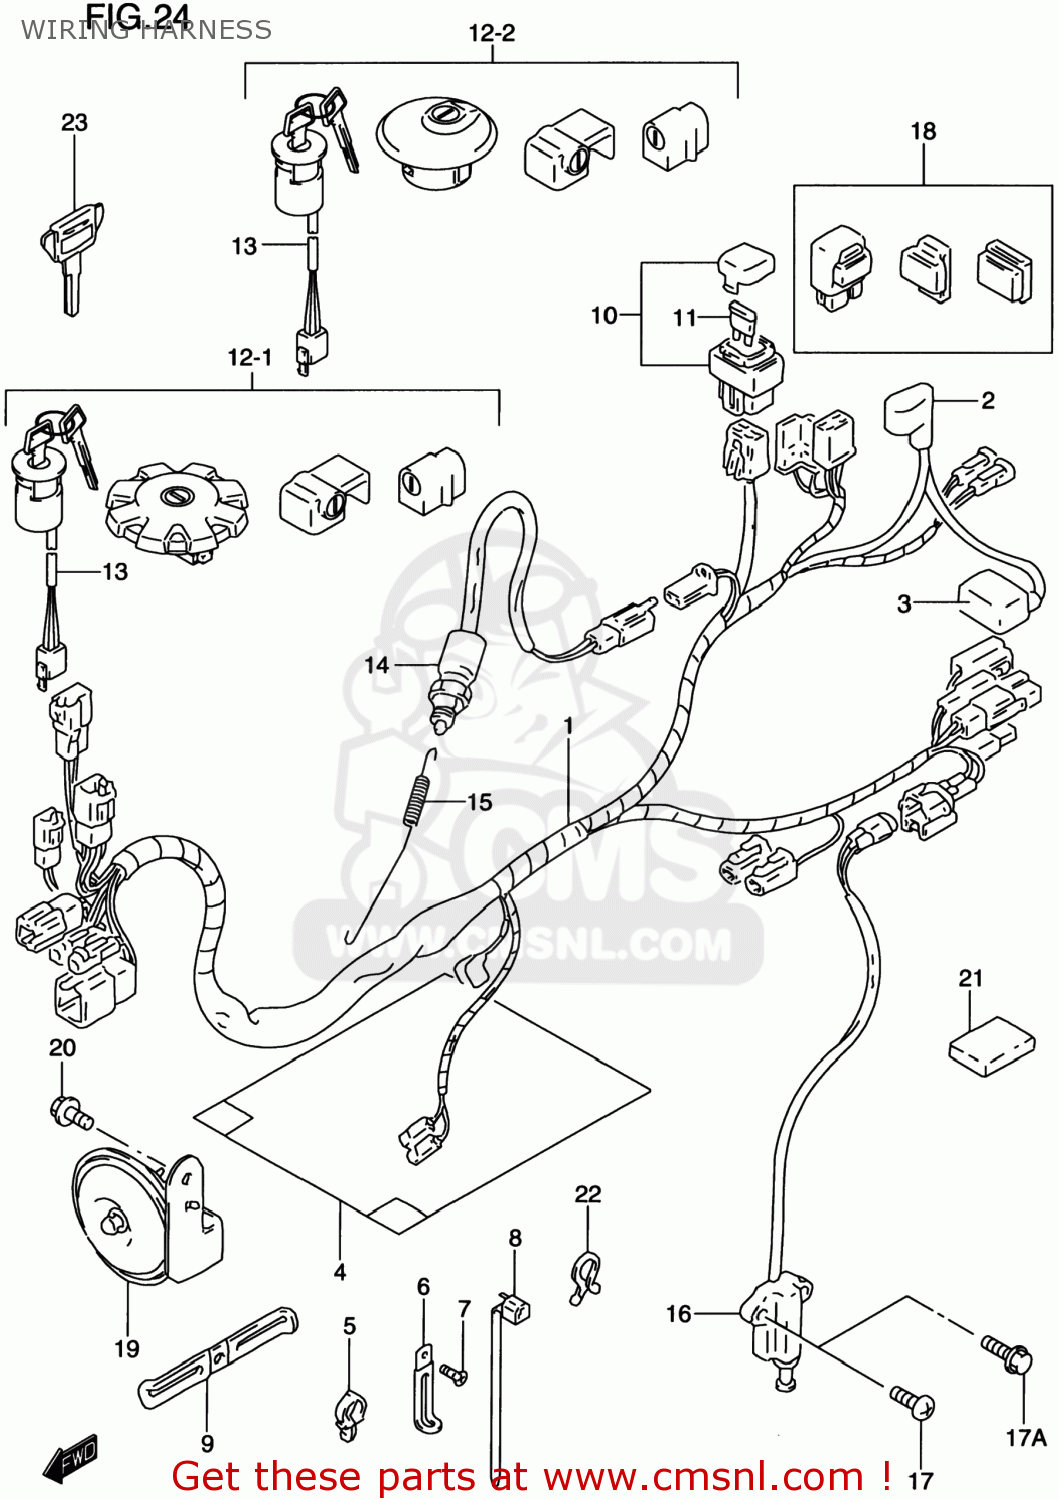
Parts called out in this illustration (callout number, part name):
1	HARNESS,WIRING
2	CAP,STARTER RELAY
3	CAP,BATTERY PLUS
4	COVER,WIRING HARNESS
5	CLAMP
6	CLAMP(L:45)
7	SCREW
8	CLAMP(L:95)
9	CLAMP,STARTER MOTOR LEAD
10	BOX ASSY,FUSE
11	FUSE(20A)
12	LOCK SET
13	SWITCH ASSEMBLY,IGNITION
14	SWITCH ASSY,STOP LAMP
15	SPRING
16	SWITCH ASSY,SIDE STAND
17	SCREW
17A	BOLT
18	RELAY ASSY
19	HORN ASSY
20	BOLT
21	PROTECTOR,WIRING HARNESS
22	CLIP(ID:11.5)
23	KEY,BLANK(TYPE:C)
